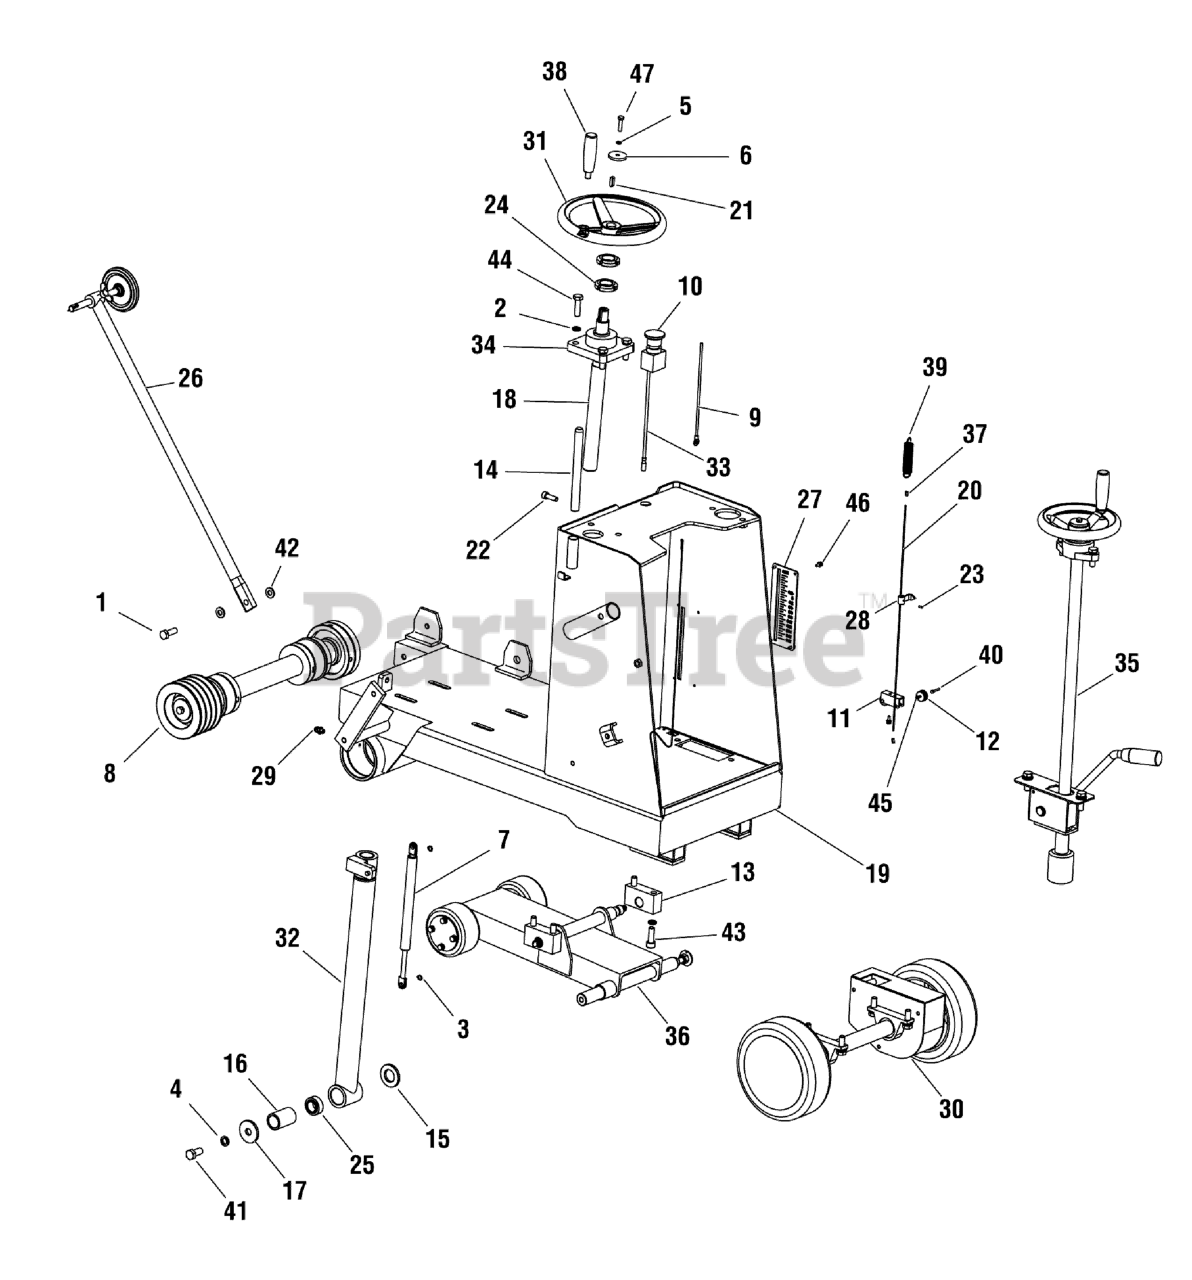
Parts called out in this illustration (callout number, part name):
1	BOLT, Hex, M10 x 30
2	WASHER, Spring
3	CIRCLIP
4	WASHER, Spring
5	WASHER, Spring
6	WASHER, Flat
7	SPRING, Gas
8	BLADE SHAFT ASSEMBLY
9	GROUND WIRE
10	EMERGENCY BUTTON
11	FIXING RACK, Guide Pulley
12	GUIDE PULLEY
13	WHEEL MOUNTING SEAT
14	LIMIT ROD
15	WASHER, Flat
16	BUSHING
17	WASHER, Flat
18	THREAD
19	PLATE, Engine
20	WIRE ROPE
22	SCREW, Socket Head, M8 x 25
23	SCREW, Flat Point, M3 x 8
24	NUT, Round
25	BEARING
26	GUIDE ROD ASSEMBLY
27	DEPTH CARD
28	DEPTH POINTER
29	NOZZLE, Grease
30	REAR WHEEL ASSEMBLY
31	HANDLE, Wheel, Nylon
32	THREAD
33	PARKING LINE
34	BEARING
35	SEMI-AUTO ASSEMBLY
36	WHEEL FRAME ASSEMBLY
37	WIRE CLAMP
38	HANDLE
39	SPRING
40	BOLT, Hex, M3 x 20
41	BOLT, Hex, M12 x 25
42	SPRING, Belleville, A20
43	SCREW, Socket Head, M10 x 30
44	BOLT, Hex, M10 x 35
45	NUT, Hex Head, Prevailing Torque, M3
46	SCREW, Pan Head, Slotted, M4 x 12
47	BOLT, Hex, M6 x 25
